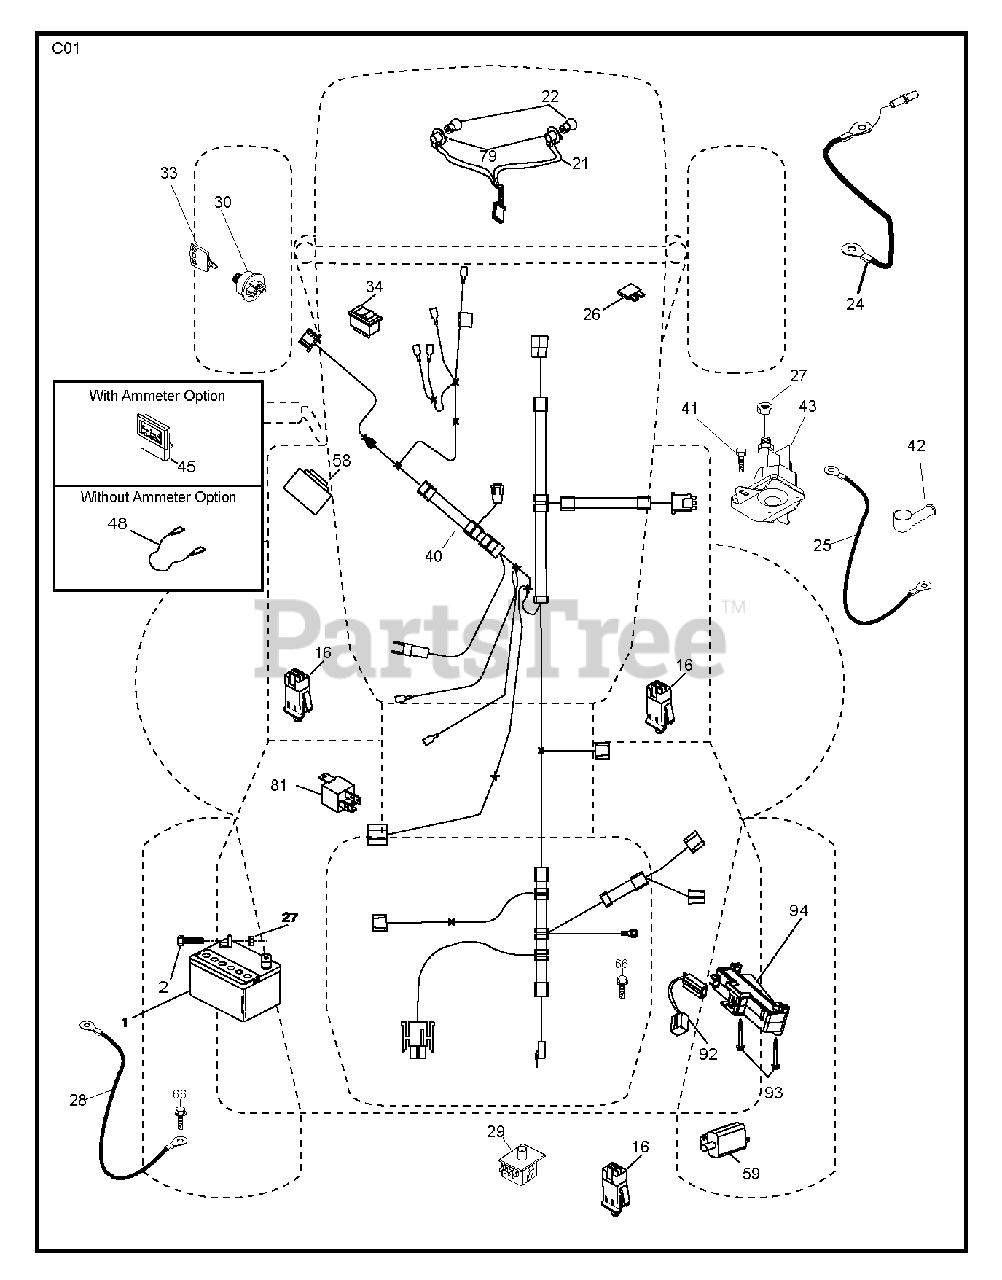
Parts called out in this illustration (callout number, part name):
1	Battery, Dry 30 Amp
2	BOLT.HEX.1/4.X.3/4.DICHROMATE
16	SWITCH INTERLOOK PUSH-IN
21	HARNESS.W/LIGHT SOCKET
24	CABLE BATTERY
25	CABLE.STARTER.6GA.11"RED
26	FUSE 20AMP
27	NUT
28	CABLE GROUND
29	SWITCH.SEAT.DP W/RAMPS
30	SWITCH.IGN.DELTA.W.LGH.ROS
33	KEY.CHAIN.BLISTER.PACK.GEN.INT
41	BOLT
42	TERMINAL COVER
43	SOLENOID.W/BRASS.PLUNGER
48	ADAPTER.AMMETER
58	BUZZER
59	.WITCH.FULL BAGGER.INDICATOR
79	BULB HOLDER ASM.
81	RELAY.ASSY.T
92	HARNESS.PIGTAIL.CONSLE
93	SCREW.PLASTITE
94	MODULE.REVERSE.ROS
